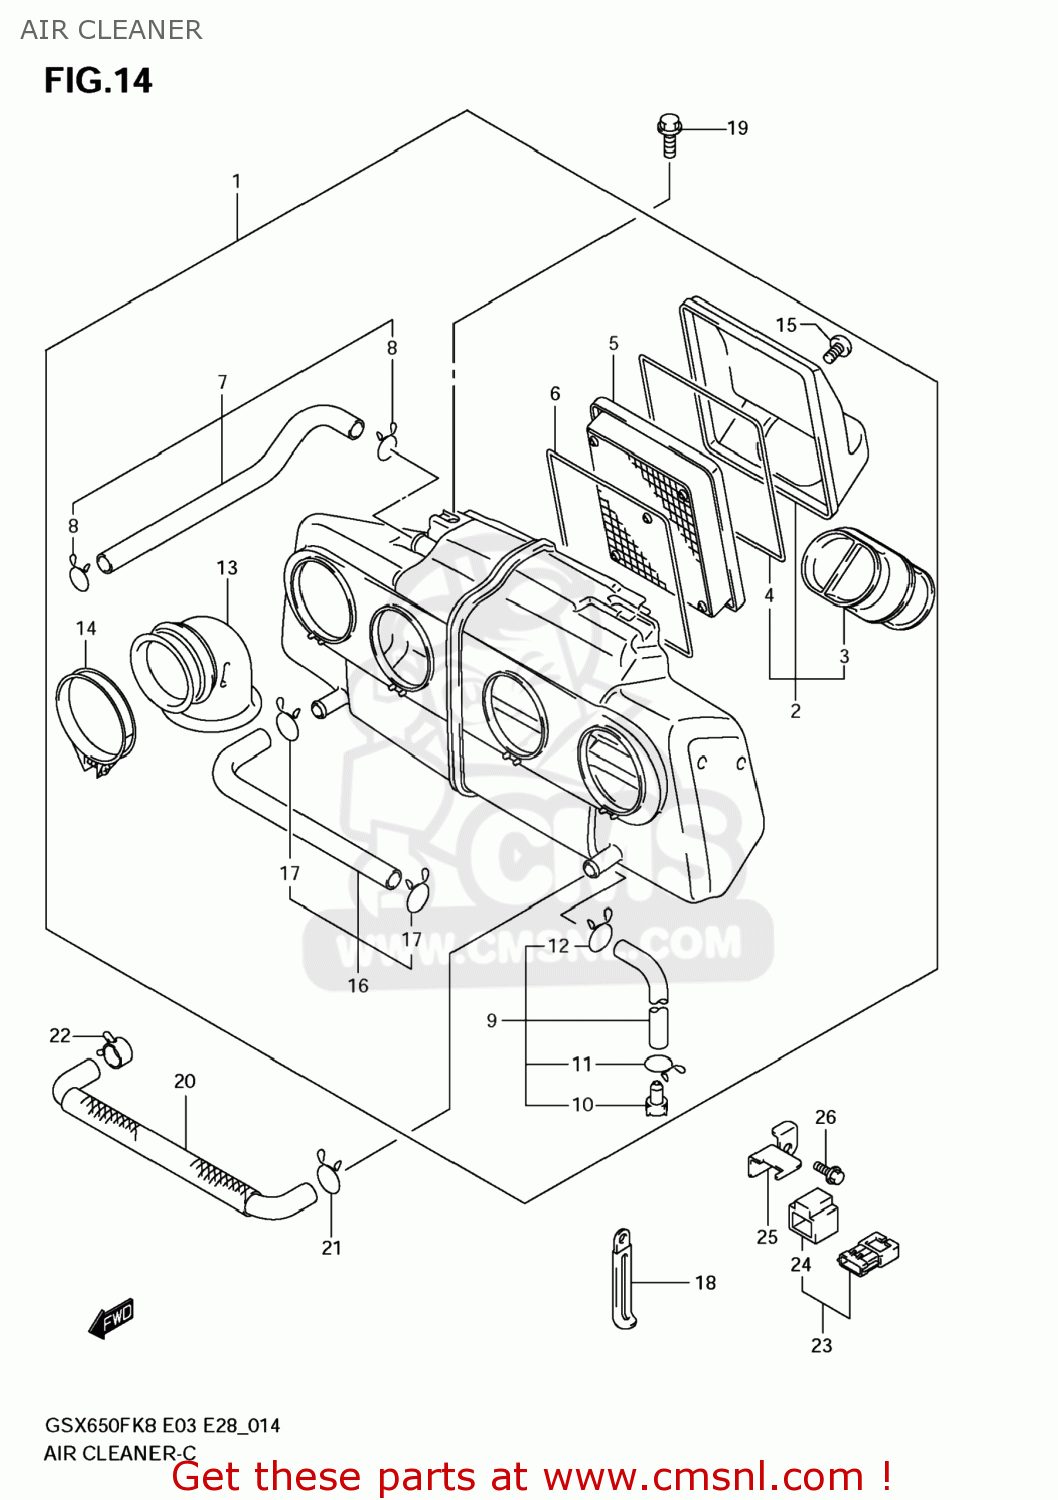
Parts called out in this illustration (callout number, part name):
1	CLEANER ASSY,A
2	CAP,AIR CLEANER
3	TUBE,INLET
4	GASKET (NAS)
5	FILTER ASSY
6	GASKET (NAS)
7	TUBE,BREATHER
8	CLIP
9	TUBE,DRAIN
10	PLUG
11	CLIP
12	CLIP
13	TUBE,OUTLET
14	CLAMP
15	SCREW
16	TUBE
17	CLIP
18	CLAMP(L:97)
19	BOLT
20	HOSE,ISC VALVE
21	CLIP
22	CLIP
23	SENSOR,BOOST
24	COVER
25	BRACKET,BOOST SENSOR
26	BOLT
